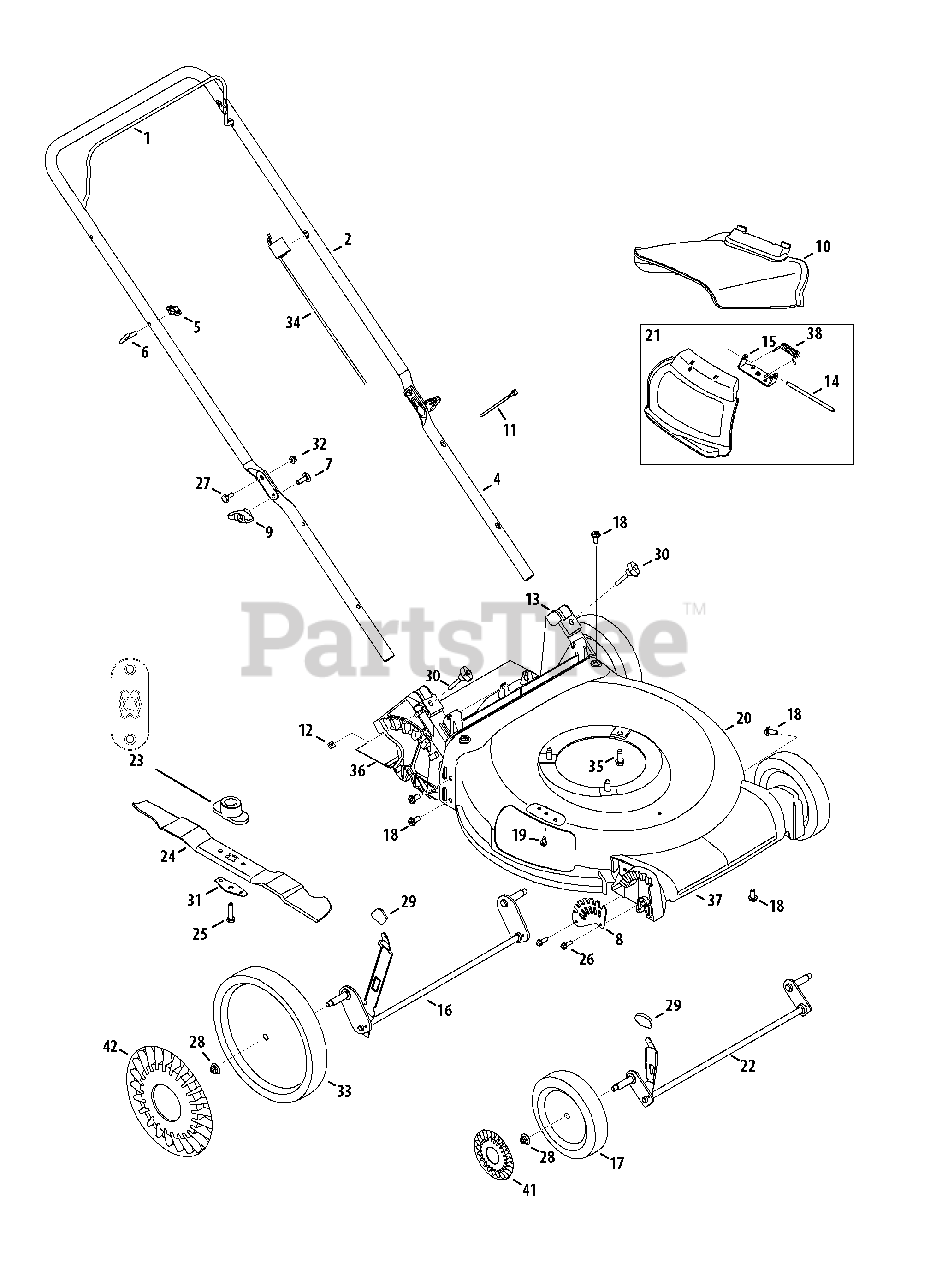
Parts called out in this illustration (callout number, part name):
1	Blade Control Handle - Black
2	Upper Handle - Black (adjustable)
4	Lower Handle
5	Knob 1/4-20
6	Rope Guide Bolt
7	Carriage Bolt 5/16-18
8	Front Height Adjustment Plate
9	Wing Knob 5/16-18 Black
10	Chute Deflector (w/clip)
11	Cable Tie
12	Sq. Nut 1/4-20
13	Rear Baffle
14	Hinge Pin
15	Chute Deflector Bracket
16	Rear Axle Ass’y - 11" wheel
17	Wheel Ass’y 7 x 2.0 Sleeve Zag Black
18	Hex Hd. Cap Scr. 5/16-14 x .75
19	Sems TT Scr. 1/4-20 x .50
20	21" Deck Ass’y
21	Hinged Mulch Plug Ass’y
22	Front Axle Ass’y - 7 " wheel
23	Blade Adapter
24	21" Mulching Blade
25	Hex Bolt 3/8-24 x 1.5" Lg. (Gr 8)
26	Screw, 1/4-15 x .750
27	Shoulder Screw .375 x .126 x 1/4-20
28	Flange Locknut 3/8-16 Gr. F Nylon
29	Knob (Black)
30	Knob 1/4-20 x 1.725 Black
31	Blade Bell Support
32	Flanged Lock Nut 1/4-20 Gr. F Nylon
33	Wheel Ass’y 11 x 2 SL: Zag Black
34	Control Cable, 140 cc B&S
35	Hex Wash HD Tap Scr 3/8-16 x 1.0
36	Trailing Shield 4.54 x 17.37
37	Front Axle Cover
38	Torsion Spring
41	Hub Cap (11")
42	Hub Cap (7")
